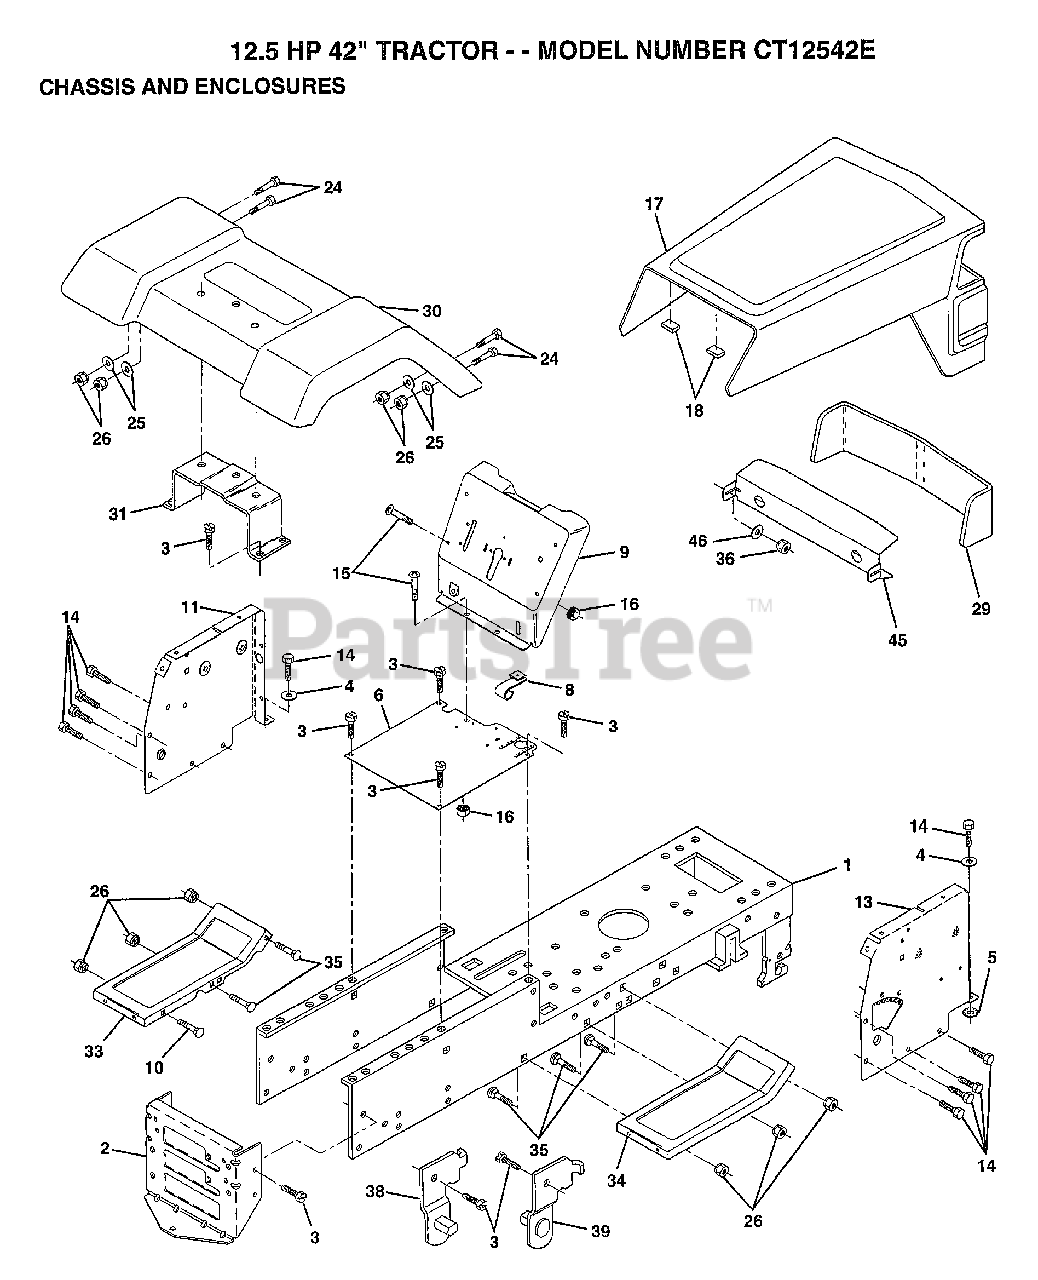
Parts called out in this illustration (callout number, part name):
3	SCREW
4	WASHER
5	LOCKWASHER
8	"CLIP,INSULATOR"
9	DASH SILKSCRN 1
11	DASH PANEL LH
14	SCREW LT
15	SCREW
17	HOOD/GRILLE.ASM.
24	BOLT
25	WASHER
26	NUT
31	BRKT FENDER
33	FOOTREST.LH.PERF.
34	FOOTREST.RH.PERF.
35	BOLT
36	PAL NUT LT
38	BRACKET ASM LH
39	BRACKET ASM RH
46	RETAINER
